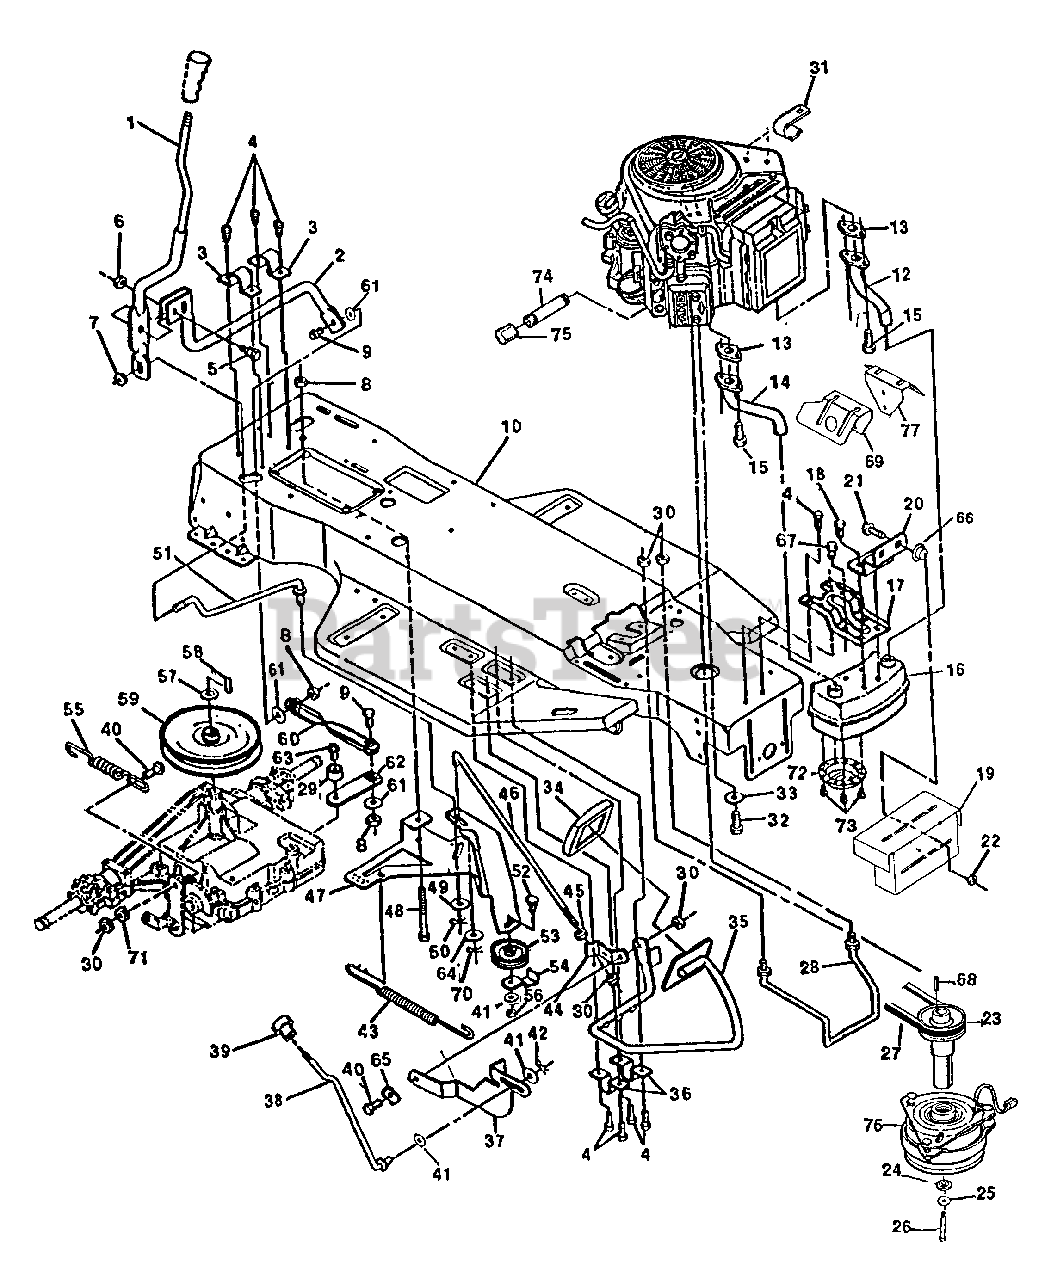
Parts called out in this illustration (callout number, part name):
1	Tube Assembly, Shift Pivot
2	Tube Assembly, Shift
3	Clip, Shift Lever
4	Screw, Hx Hd, Wshr Tap, 5/16-18 x 1/2 In.
5	Shoulder Bolt
6	Nut, Hx, Ctrlk, 1/4-20 Thd.
7	Nut, Hx, Nylon, Lock 3/8-16 Thd.
8	Nut, Hx, Ctrlk, 3/8-16 Thd.
9	Screw, 3/8-16 x 1-1/4 In.
10	Main Frame
11	Engine 14 Horsepower B&S
12	Exhaust Tube, L.H.
13	Gasket, Muffler (Engine Part)
14	Exhaust Tube, R.H.
15	Screw, Sem, Engine Part
17	Bracket Muffler
18	Screw, Hx Hd, Tap 1/4-20 X 1/2 In.
19	Heat Shield, Muffler
20	Bracket, Transaxle
21	Bolt, Carriage, 5/16-18 X 5/8 In.
22	Nut, Hx, Wd Fl, Lk 5/16-18 Thd.
23	Pulley Assembly, Engine
24	Bearing, Sleeve Sector Gear
25	Washer, Split, Lock 7/8 In.
26	Screw, Hx Hd, 7/16-20 X 5-1/2 In.
27	V-Belt, 90 In. Long
28	Belt Guide
29	Washer, Special
30	Nut, Hex, Ctrlk, 5/16-18 Thd.
31	Cable Clip
32	Screw, Hx Hd Tap, 3/8-16 X 1-1/4 In.
33	Washer, 3/8 In.
34	Pad, Clutch/Brake, Molded
35	Assembly, Clutch/Brake Arm
36	Bracket, Clutch/Brake Arm
37	Lever, Park Brake
38	Rod, Parking Brake
39	Knob, Park Brake
40	Shoulder Bolt, 5/16-18 Thd.
41	Washer, 9/16 In.
42	Cotter Pin
43	Spring, Clutch
44	Bracket, Brake Rod
45	Nut, Hx, Keps, 5/16-18 Thd.
46	Rod, Clutch
47	Arm, Idler
48	Shoulder Bolt, 3/8-16 Thd.
49	Washer, Flat, 13/32 In.
50	Hairpin
51	Rod, Shift-On-The-Go
52	Carriage Bolt, 3/8-16 x 2 In.
53	Idler Sheave, Backside
54	Belt Retainer
55	Spring, Brake
56	Nut, Flange, 3/8-16 Thd
57	Retaining Ring
58	Key, Woodruff, #606
60	Shift Link
61	Washer, Flat, 13/32 In.
62	Shift Lever, Transaxle
63	Screw, Hx Hd, 1/4-28 X 3/4 In.
64	Flatwasher
65	Washer, Wave
66	Push Nut, 5/16 Bolt Retainer
67	Screw, Hex Hd Tap, 1/4-20 x 5/8 In.
68	Key, Square 1/4
69	Air Deflector
70	Pin, Cotter
72	Deflector
73	Screw, Hx Wa Hd, #8-32 x 3/8 In.
74	Nipple, 3/8-18 x 4 In.
75	Cap, Pipe
76	Electric Clutch
77	Air Deflector
